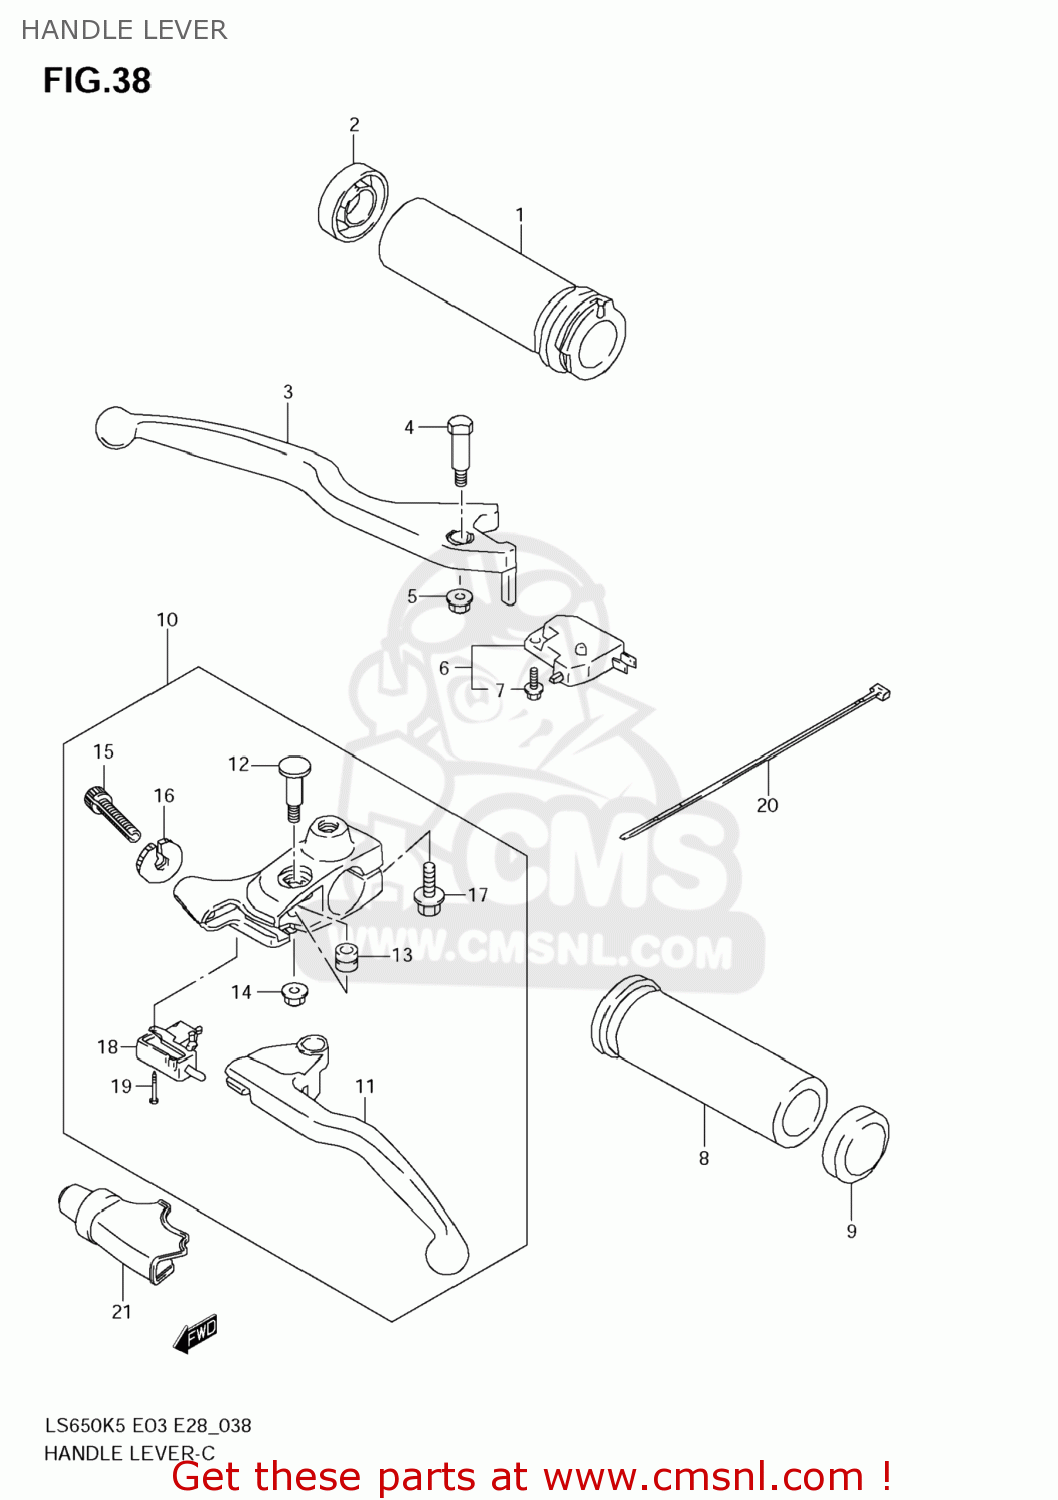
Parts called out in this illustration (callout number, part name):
1	GRIP,THROTTLE
2	CAP,GRIP END
3	LEVER,BRAKE
4	BOLT,LEVER SET
5	NUT
6	SWITCH ASSY,ST
7	SCREW
8	GRIP,L
9	CAP,GRIP END
10	LEVER ASSY,CLUTCH
11	LEVER,CLUTCH
12	BOLT,CLUTCH LEVER
13	SPACER,CLUTCH LEVER PIVOT
14	NUT
15	ADJUSTER,WIRE
16	NUT,LOCK
17	BOLT
18	SWITCH,CLUTCH
19	SCREW
20	CLAMP(L:250)
21	COVER,CLUTCH LEVER
